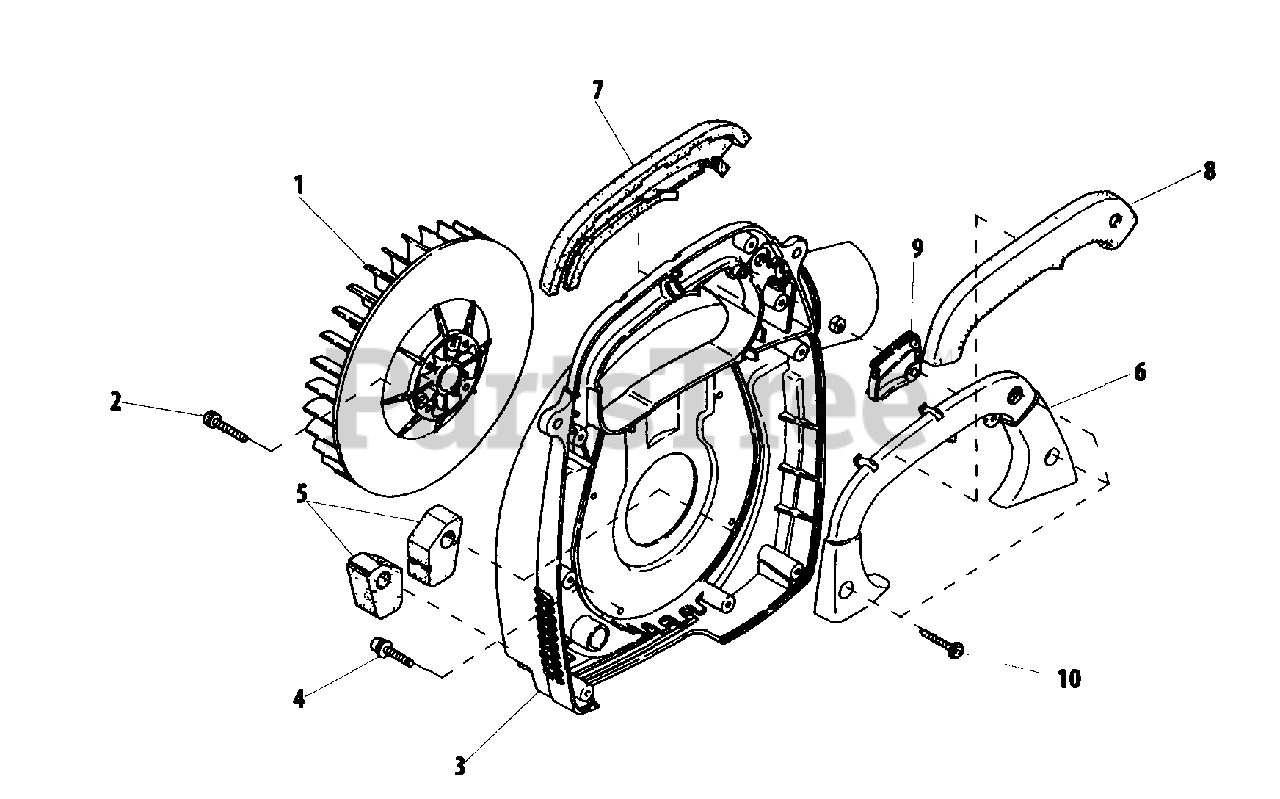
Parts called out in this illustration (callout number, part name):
1	IMPELLER
2	SCREW - 5X20
3	COVER, FAN - RIGHT
4	SCREW - 5X16
5	CUSHION - REAR
6	HANDLE
7	GRIP
8	GRIP
9	TRIGGER, THROTTLE
10	SCREW
